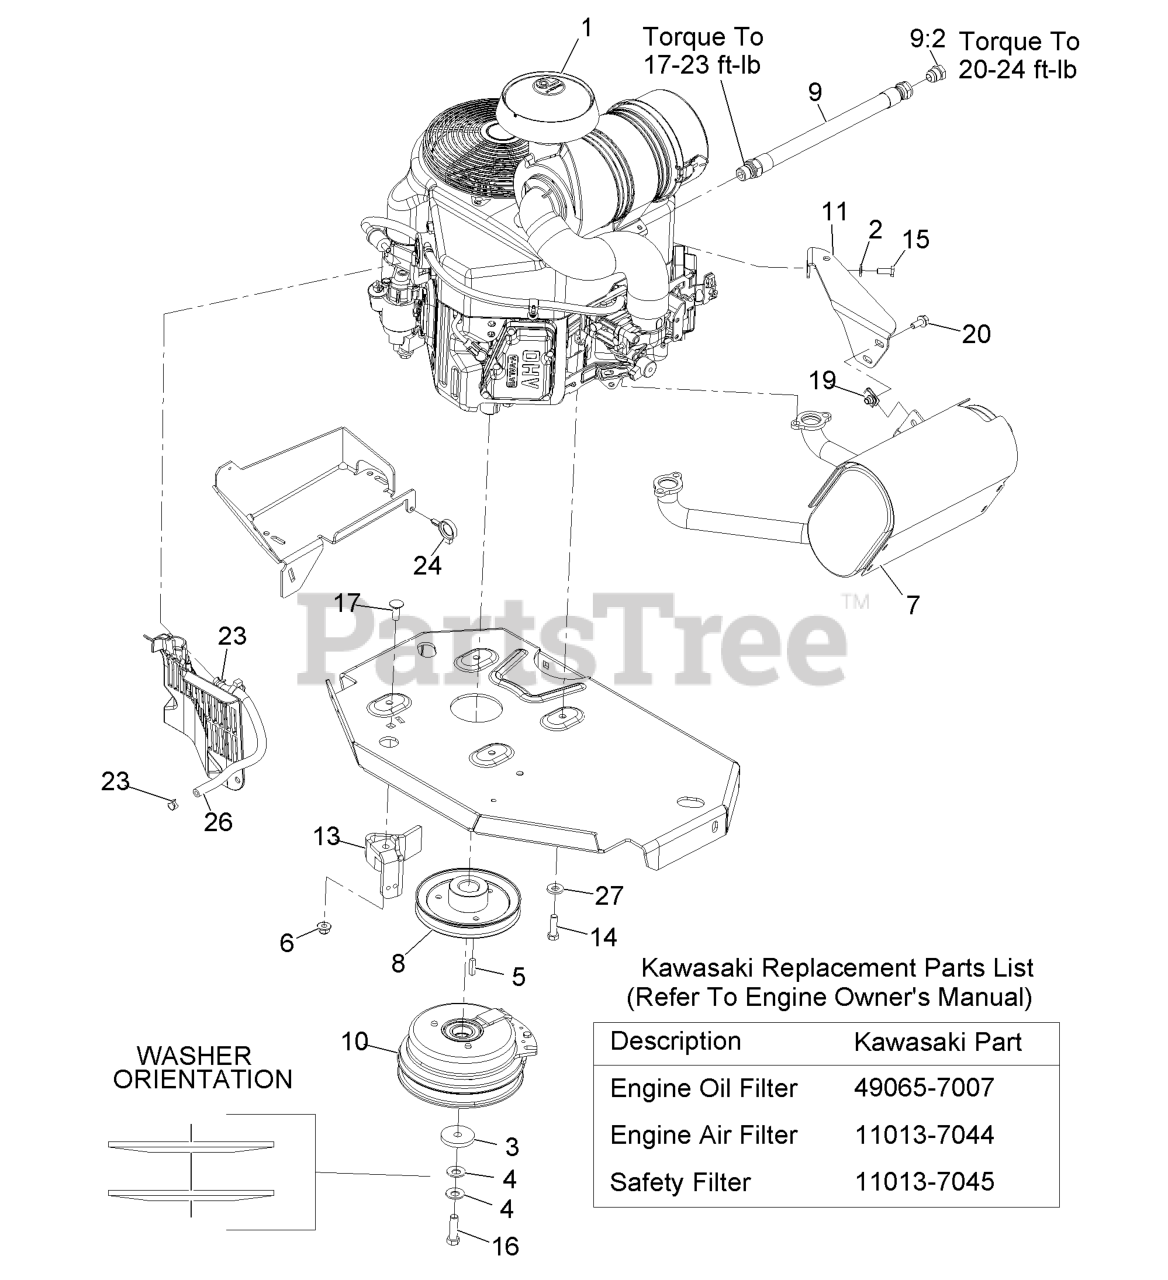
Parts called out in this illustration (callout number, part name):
1	Engine,Ka 24hp Fx Bendix
2	WASHER-SPRING
3	WASHER-CLUTCH
4	WASHER-SPRING
6	NUT-HF, NI
7	MUFFLER
8	SHEAVE-PUMP, DRIVE
11	BRACKET-MUFFLER
13	CLUTCH-ANCHOR
14	SCREW-HH
15	SCREW-HH
16	SCREW-HH 7/16-20 X 1 1/2 W/LOCTITE
17	SCREW-CARR
20	SCREW-HHF
23	CLAMP-HOSE
24	CLAMP-HOSE
26	HOSE-FUEL
27	WASHER-BELLEVILLE
